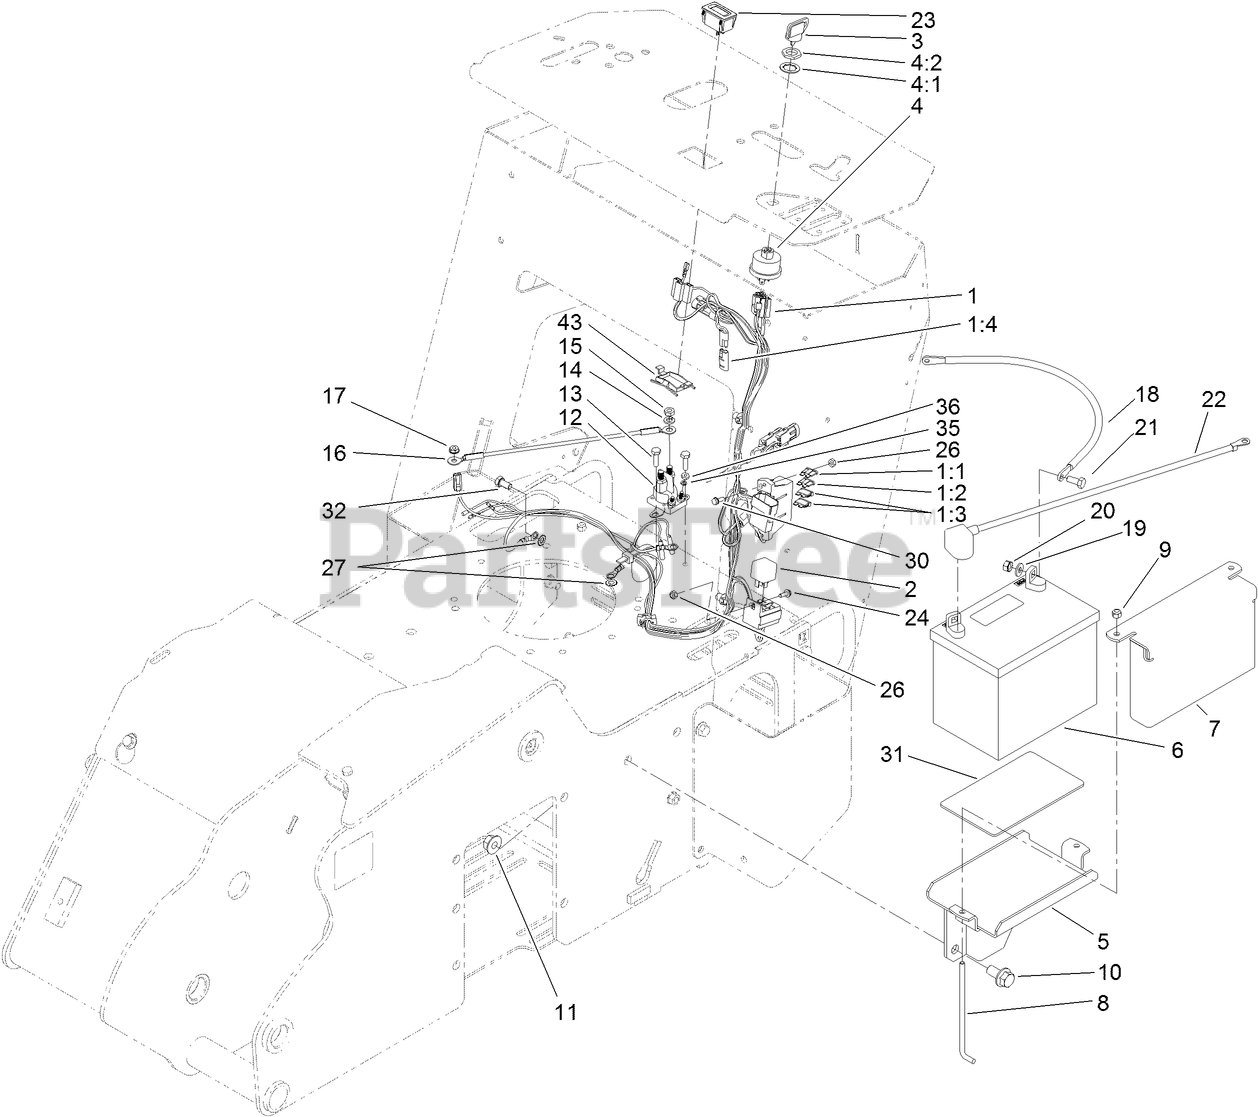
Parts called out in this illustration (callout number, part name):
1	HARNESS-WIRE
1:1	FUSE-BLADE, 30 AMP
1:2	FUSE-BLADE, 25 AMP
1:3	FUSE-BLADE, 15 AMP
1:4	CAP-PLUG
2	RELAY
3	KEY-IGNITION
4	Key Switch ASM
4:1	WASHER-TOOTH, INTERNAL
4:2	NUT-HH
5	TRAY-BATTERY
6	BATTERY-DRY
7	PLATE-HOLD DOWN, BATTERY
8	HOLDOWN-BATTERY
9	NUT-LOCK, NI
10	SCREW-HHF
11	NUT-HHF
12	SOLENOID
13	SCREW-HH
14	WASHER-LOCK
15	NUT-JAM
16	WIRE-SOLENOID/STARTER
17	NUT-KEPS
18	CABLE-BATTERY, RED
19	WASHER-FLAT
20	NUT-KEPS
21	SCREW-HH
22	CABLE-BATTERY, BLACK
23	HOURMETER
26	NUT-LOCK, NI
27	WASHER-LOCK
30	SCREW-HWH
31	PAD-SKID, ANTI
32	SCREW-HH
35	WASHER-LOCK
36	NUT-HEX
43	CLIP-MOUNTING
